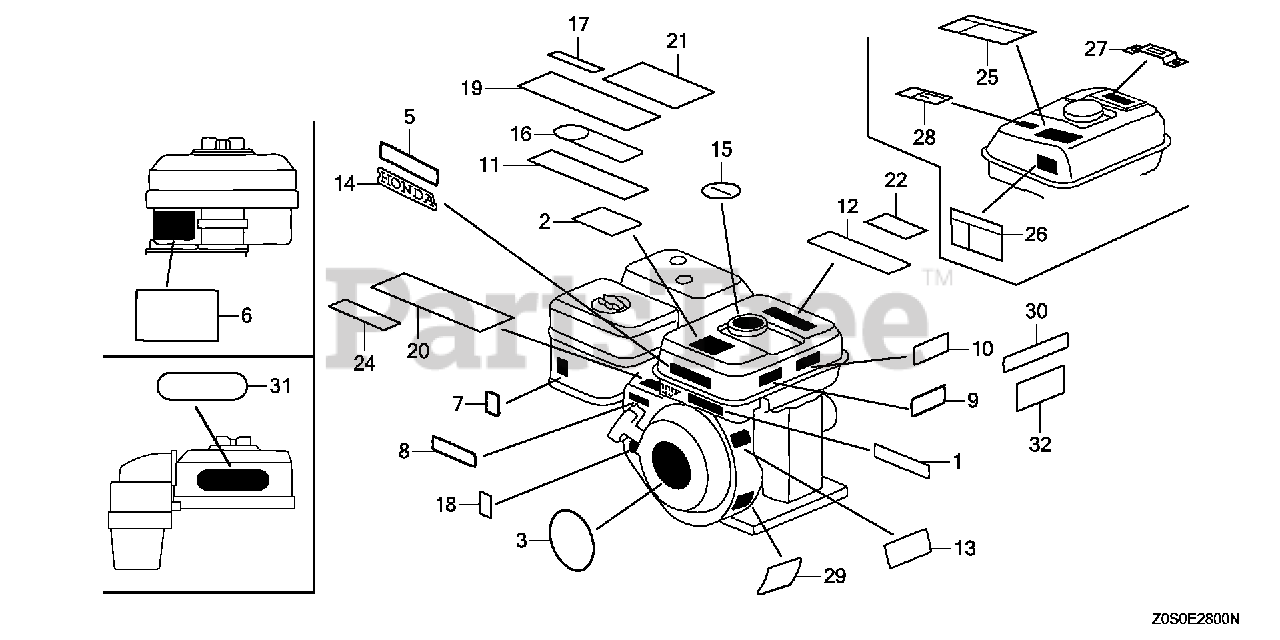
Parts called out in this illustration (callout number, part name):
3	EMBLEM (GX120)
5	LABEL, CAUTION
7	MARK, CHOKE
